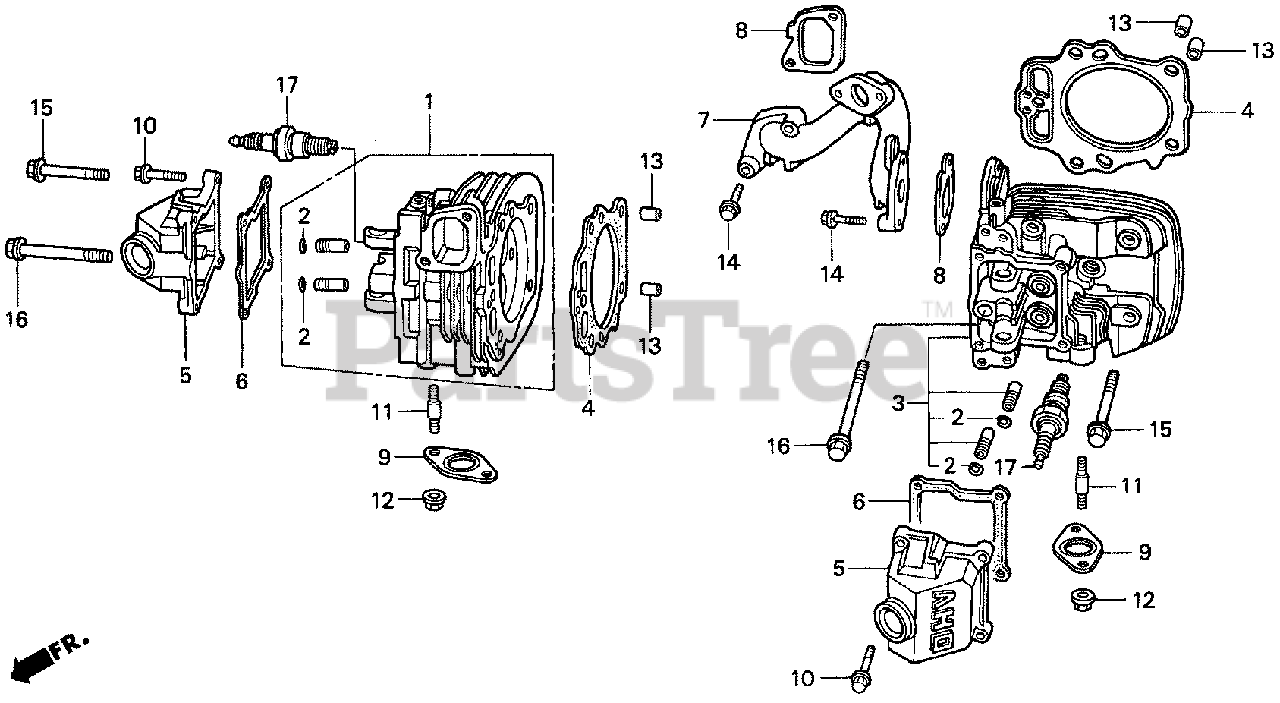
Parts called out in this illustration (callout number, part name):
1	CYLINDER HEAD (#1)
2	CLIP, VALVE GUIDE
3	CYLINDER HEAD (#2)
4	GASKET, CYLINDER HEAD
5	COVER, HEAD
6	GASKET, HEAD COVER
7	MANIFOLD, IN.
8	GASKET, IN. MANIFOLD
9	GASKET, EX. PIPE
10	BOLT, FLANGE (6X25) (CT200)
11	BOLT, STUD (8X25)
12	NUT, FLANGE (8MM)
13	PIN A, DOWEL (12X20)
14	BOLT, FLANGE (6X32)
15	BOLT, FLANGE (10X75)
16	BOLT, FLANGE (10X130)
17	SPARK PLUG (BPR5ES) (NGK)
